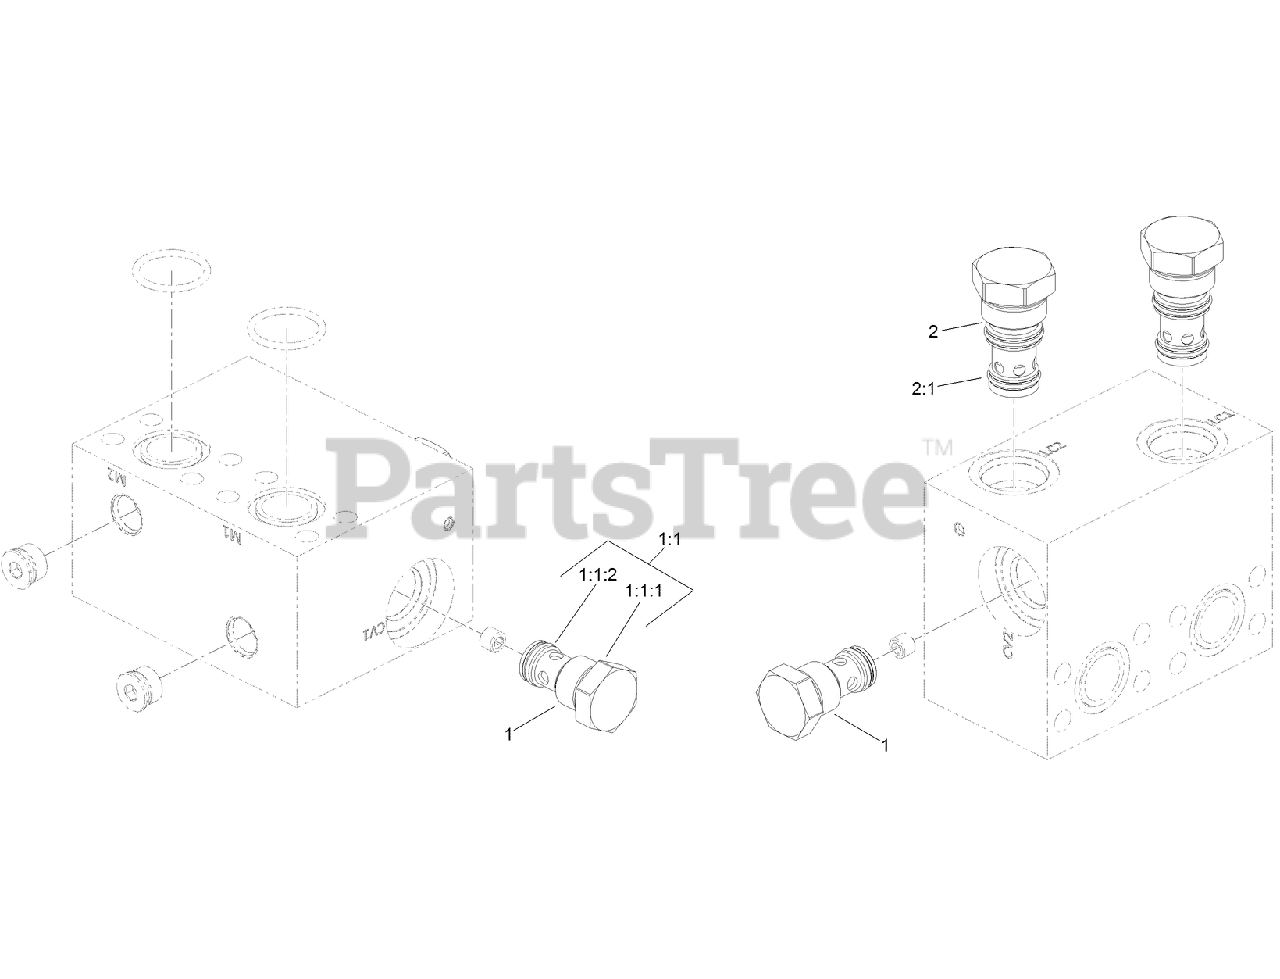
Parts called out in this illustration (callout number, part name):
1	VALVE-CHECK
1:1	SEAL KIT
2	VALVE-LOGIC, ELEMENT
2:1	SEAL KIT
